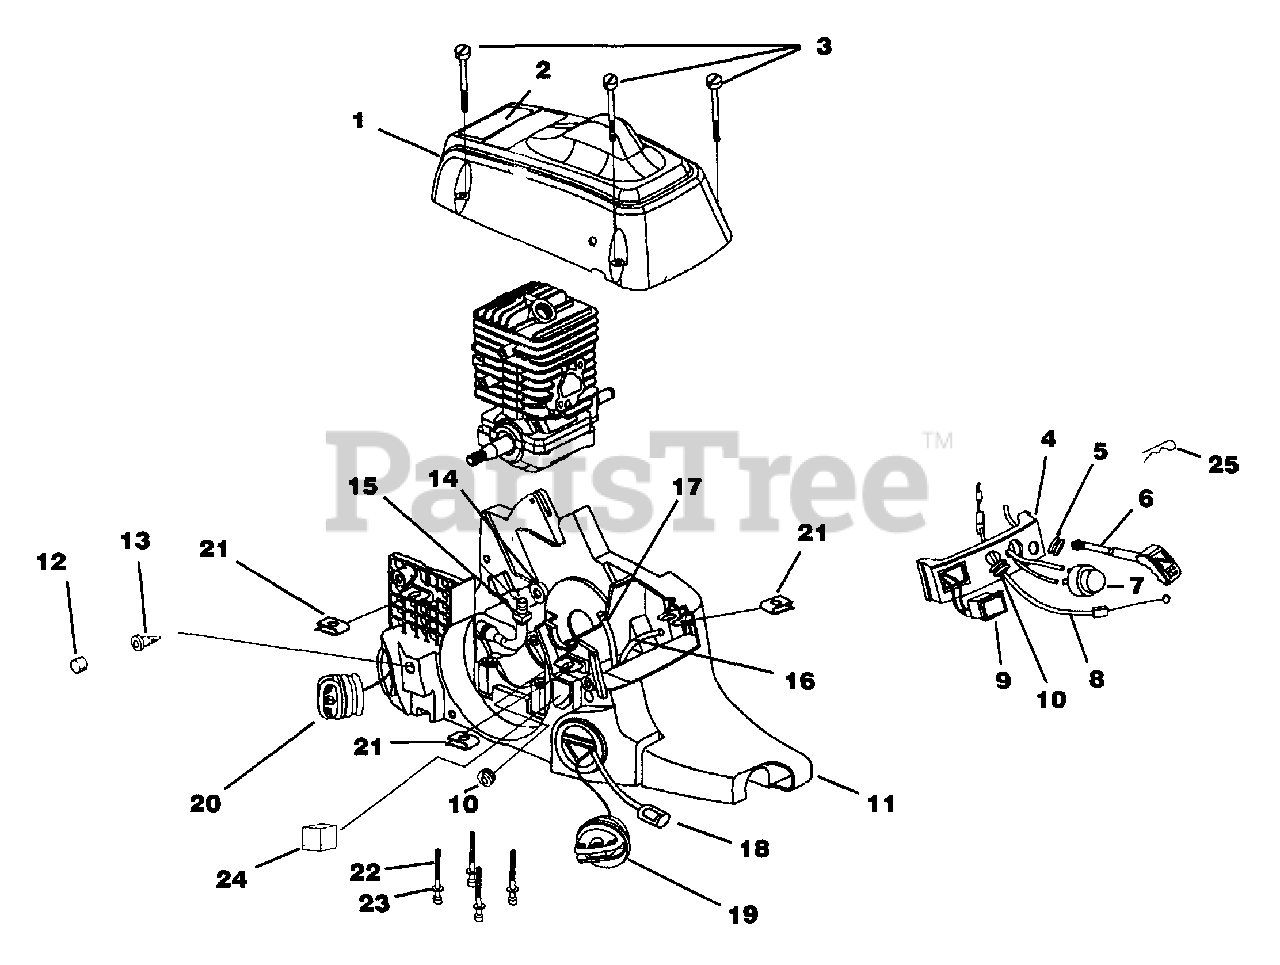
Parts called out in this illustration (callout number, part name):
1	Cylinder Cover Kit
2	Safety Decal
3	Screw-Slotted Pan Hd.
4	Control Panel
5	Grommet
6	Rod, Choke
7	Bulb, Air Purge
8	Throttle Cable
9	Switch, Rocker
10	Grommet - Split
11	Engine Housing Assembly
12	Element, Filter (Bronze)
13	Duck Bill Valve
14	Oil Outlet Grommet
15	Oil Intake Tube
16	Rubber Tubing (5 1/2")
17	Rubber Tubing (8 1/2")
18	Fuel Filter
19	Fuel Cap w/Retainer
20	Oil Cap w/Retainer
21	Speed Nut ("U-Type")
22	Screw, Cap-Socket Hd. (10-24 x 2")
23	Washer
24	Pre Filter
25	Spring Clip (Choke Rod)
